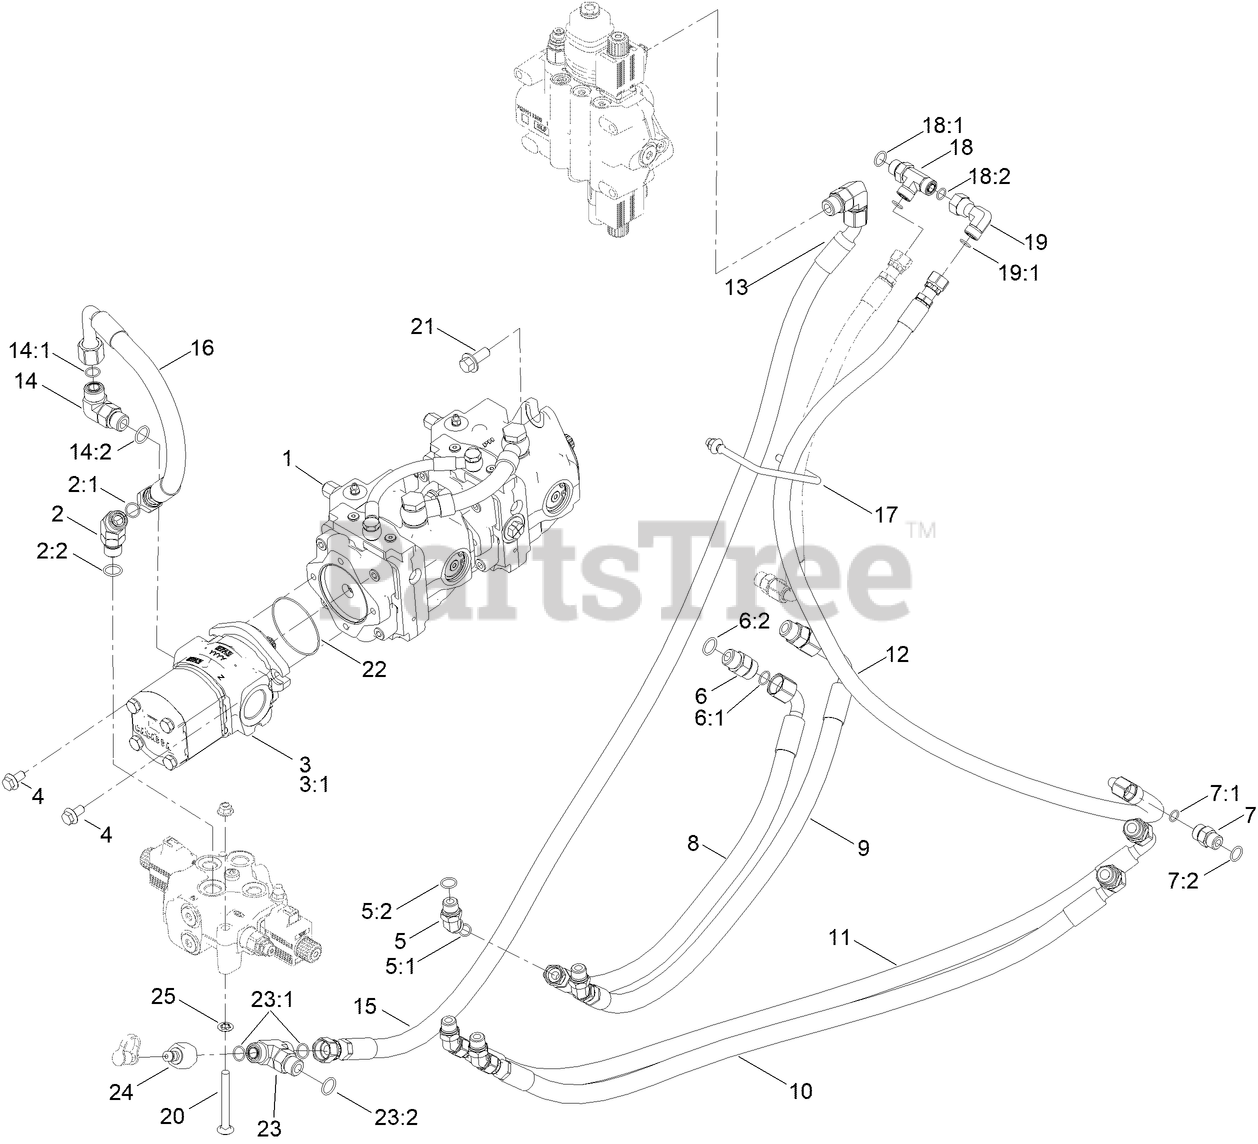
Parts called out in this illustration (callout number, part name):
1	PUMP-TANDEM
2	FITTING-HYD, 45 DEG
2:1	O-RING
2:2	O-RING
3	GEAR PUMP ASM
3:1	KIT-SEAL,
4	SCREW-HHF
5	FITTING-HYD, 45 DEG
5:1	O-RING
5:2	O-RING
6	FITTING-STRAIGHT
6:1	O-RING
6:2	O-RING
7	FITTING-STRAIGHT
7:1	O-RING
7:2	O-RING
8	HYD HOSE ASM
9	HYD HOSE ASM
10	HYD HOSE ASM
11	HYD HOSE ASM
12	HYD HOSE ASM
13	HOSE-HYD
14	FITTING-ELBOW, 90 DEG
14:1	O-RING
14:2	O-RING
15	HYD HOSE ASM
16	HYD HOSE ASM
17	GUIDE-HOSE
18	FITTING-TEE
18:1	O-RING
18:2	O-RING
19	FITTING-HYD
19:1	O-RING
20	SCREW-HFH
21	SCREW-HFH
22	O-RING
23	TEE-ADAPTER
23:1	O-RING
23:2	O-RING
24	NIPPLE
25	NUT-PUSH
